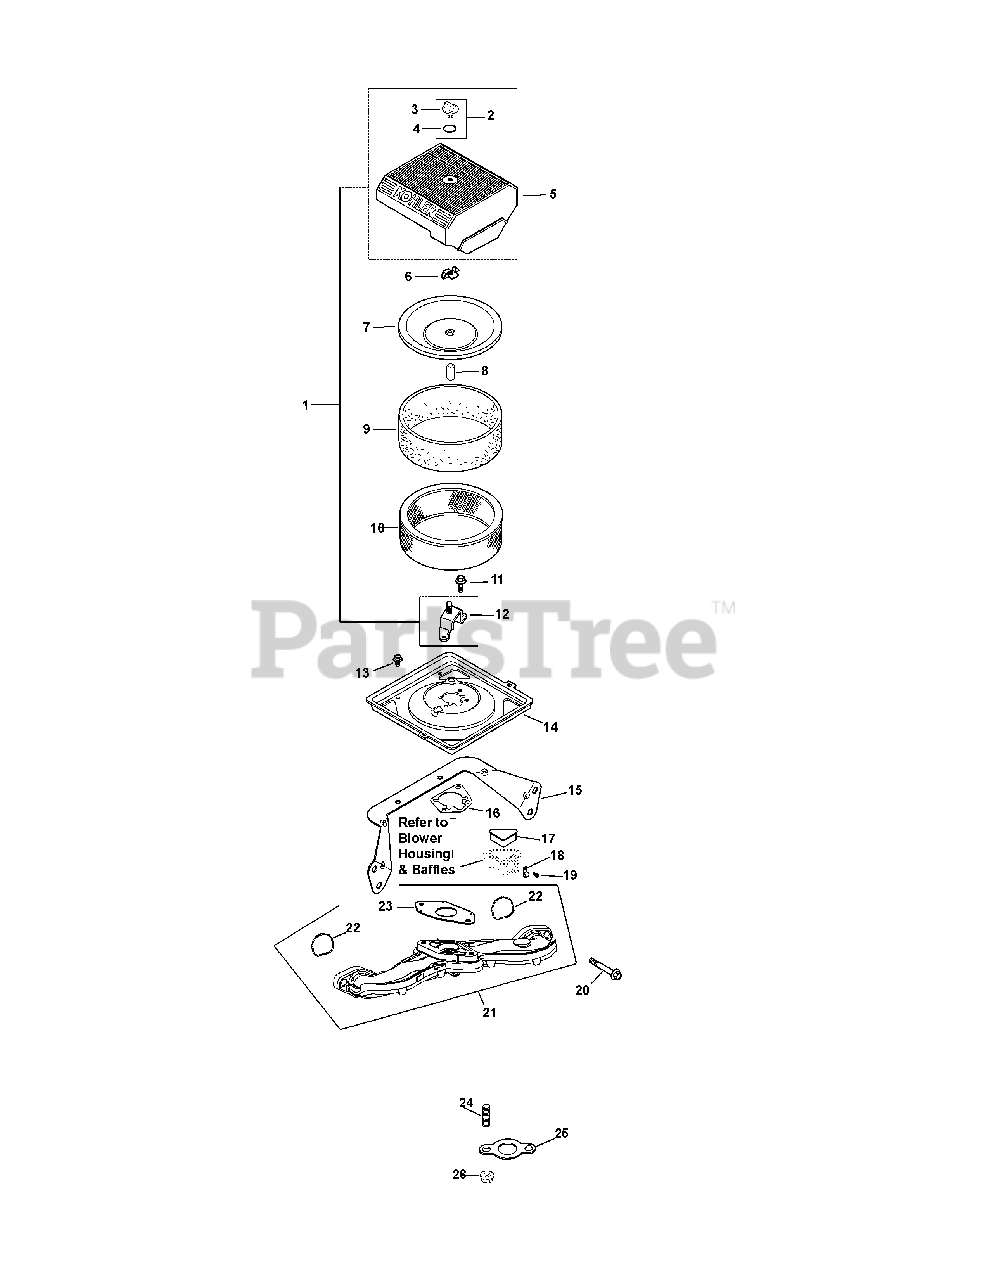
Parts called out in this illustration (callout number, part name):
1	Kit, air cleaner cover (Incl 2 5,12)
2	Kit, knob w/seal (Includes 3,4)
5	Cover, air cleaner
7	Cover, inner air cleaner
8	Seal, inner air cleaner
9	Element, precleaner
10	Element, air cleaner
11	Screw, flg thd frm M6x1.0x16
12	Bracket, air cleaner
13	Screw, flg thd frm M5x0.8x10
14	Base, air cleaner
15	Bracket, air cleaner base
16	Gasket, air cleaner base
17	Cover, blower housing
19	Screw, wsh hd tap #8-18x1/2"
20	Screw, flg M6x1.0x40
21	Manifold, intake - plastic (Includes 22 & 23)
22	O-Ring, intake port
23	Gasket, carburetor
24	Stud M8x1.25x33 (4)
25	Gasket, exhaust manifold (2)
26	Nut, hex. flange M8x1.25 (5)
